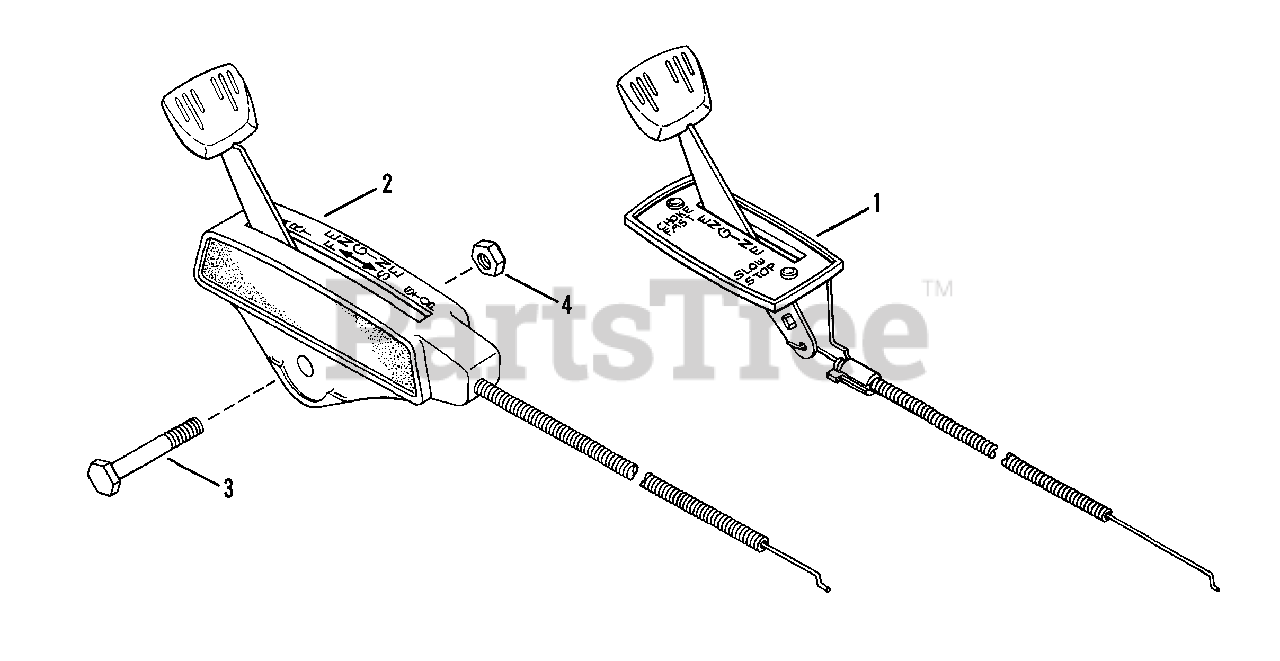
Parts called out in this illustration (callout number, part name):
1	CONTROL, Throttle
2	CONTROL, Throttle
3	CAPSCREW, 1/4Fx1 3/4" Hex Head
4	LOCKNUT, 1/4-28 Hex
